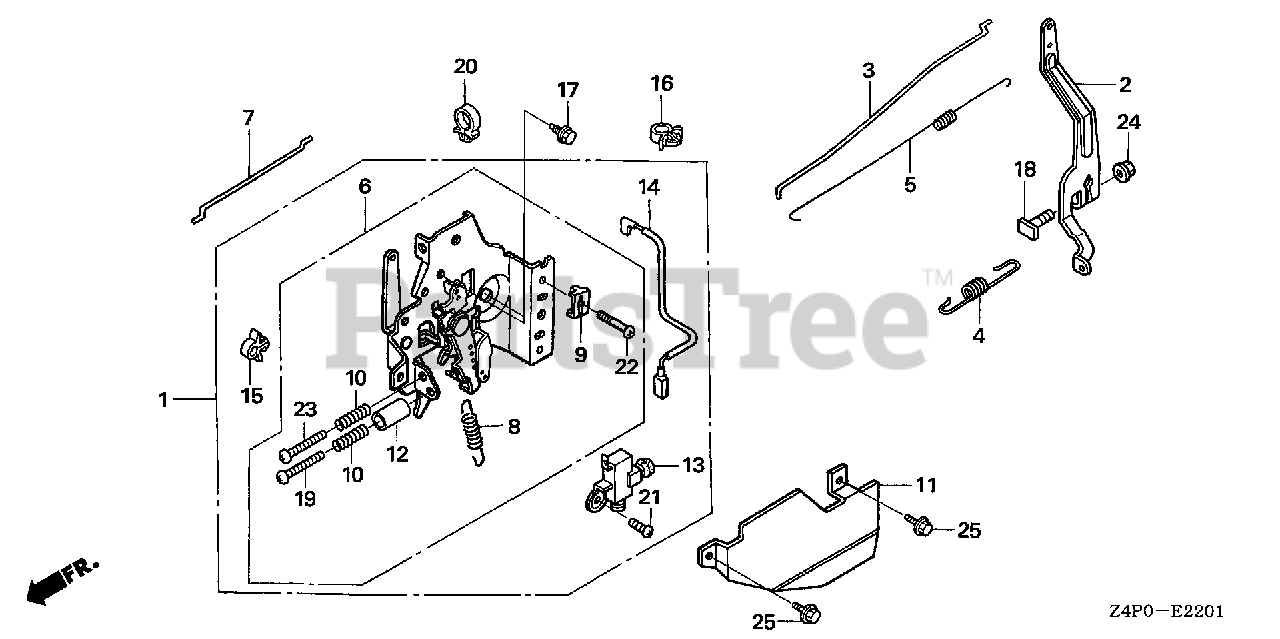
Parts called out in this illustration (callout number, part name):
1	CONTROL ASSY. (STD) (EN)
2	ARM, GOVERNOR
3	ROD, GOVERNOR
4	SPRING, GOVERNOR
5	SPRING, THROTTLE RETURN
6	CONTROL (STD)
7	ROD, CHOKE
8	SPRING, LEVER
9	HOLDER, CABLE
10	SPRING, CONTROL ADJUSTING
11	PROTECTOR, CONTROL
12	COLLAR, STOPPER
13	SWITCH ASSY., ENGINE STOP
14	WIRE, STOP SWITCH
15	HOLDER, STOP SWITCH WIRE
16	CLAMP, HARNESS
17	BOLT, FLANGE (6X12) (CT200)
18	BOLT, GOVERNOR ARM
19	SCREW, RECESSED (5X28)
20	CLIP, HARNESS
21	SCREW, PAN (4X8)
22	SCREW, PAN (5X16)
23	SCREW, PAN (5X20)
24	NUT, FLANGE (6MM)
25	BOLT, FLANGE (6X10)
